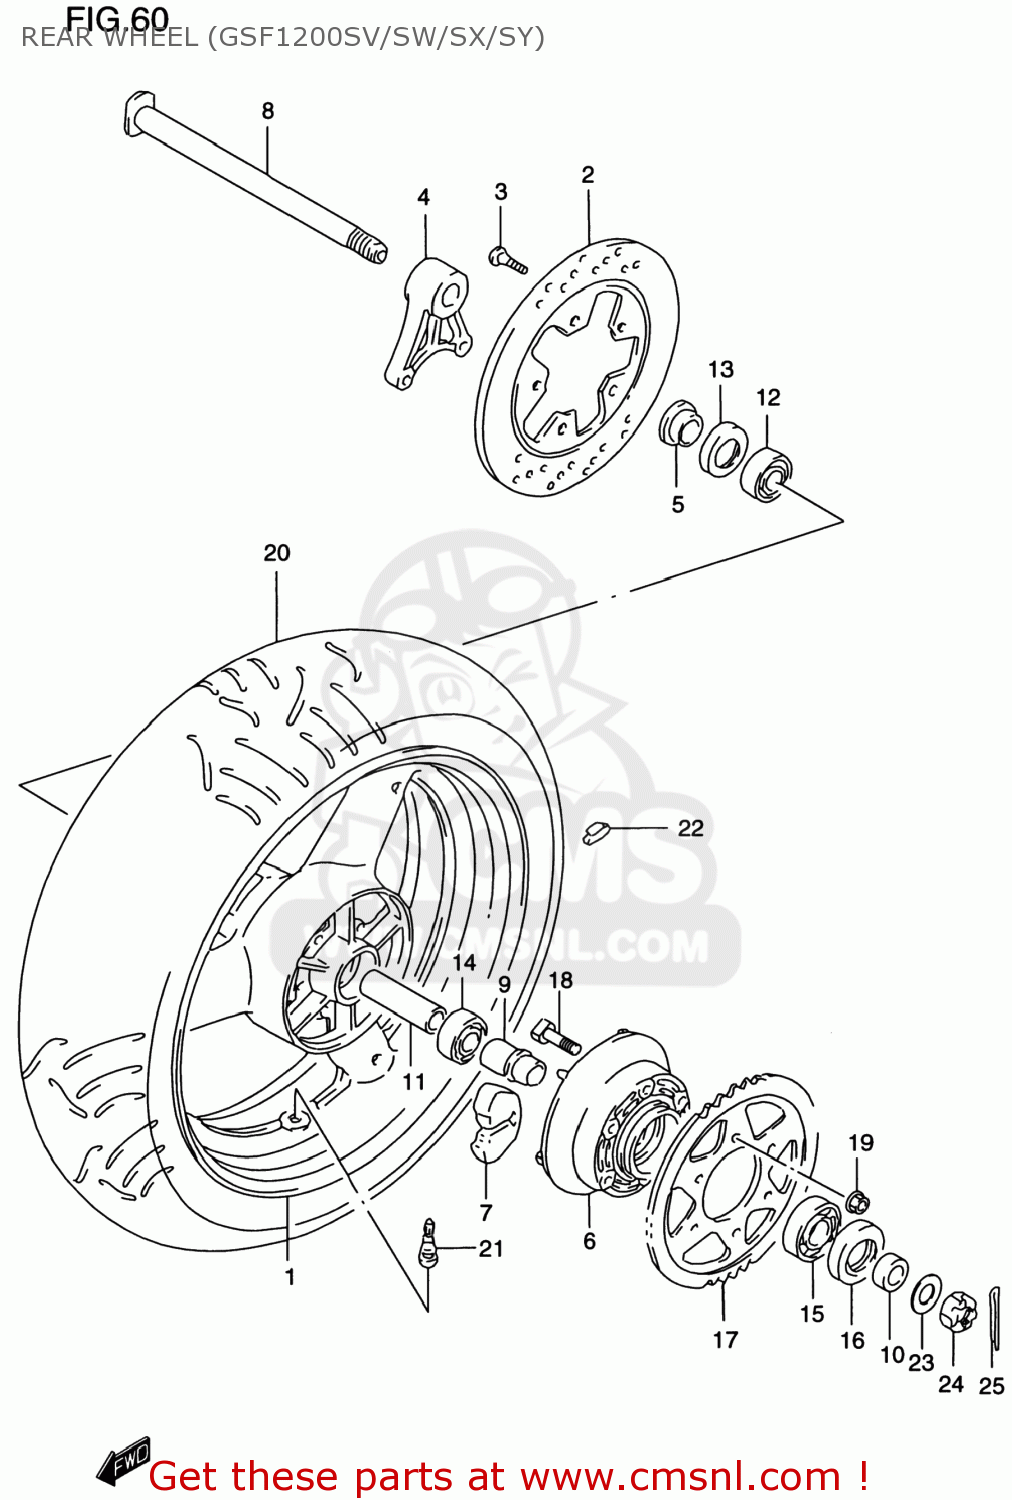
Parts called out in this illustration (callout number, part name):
1	WHEEL,REAR (MT5.50X17)(G
2	DISC,RR BRAKE
3	BOLT 8X33
4	BRACKET,RR CALIPER
5	SPACER,RR AXLE,R
6	DRUM,RR SPROCKET
7	ABSORBER,RR HUB SHOCK
8	AXLE,RR
9	RETAINER,RR HUB BEARING
10	SPACER,RR AXLE,L
11	SPACER,RR WHEEL HUB BEARING
12	BEARING(20X47X14)
13	SEAL,OIL(28X47X7)
14	BEARING(20X47X14)
15	BEARING(25X62X17)
16	SEAL,OIL(35X62X8)
17	SPROCKET,RR(NT:45-530)
18	BOLT
19	NUT
20	TIRE,RR(180/55 ZR17 73W)
21	VALVE ASSY,WHEEL RIM(TR412)
22	BALANCER,WHEEL (10G)
23	WASHER(18.5X28X2.6)
24	NUT
25	PIN, COTTER
